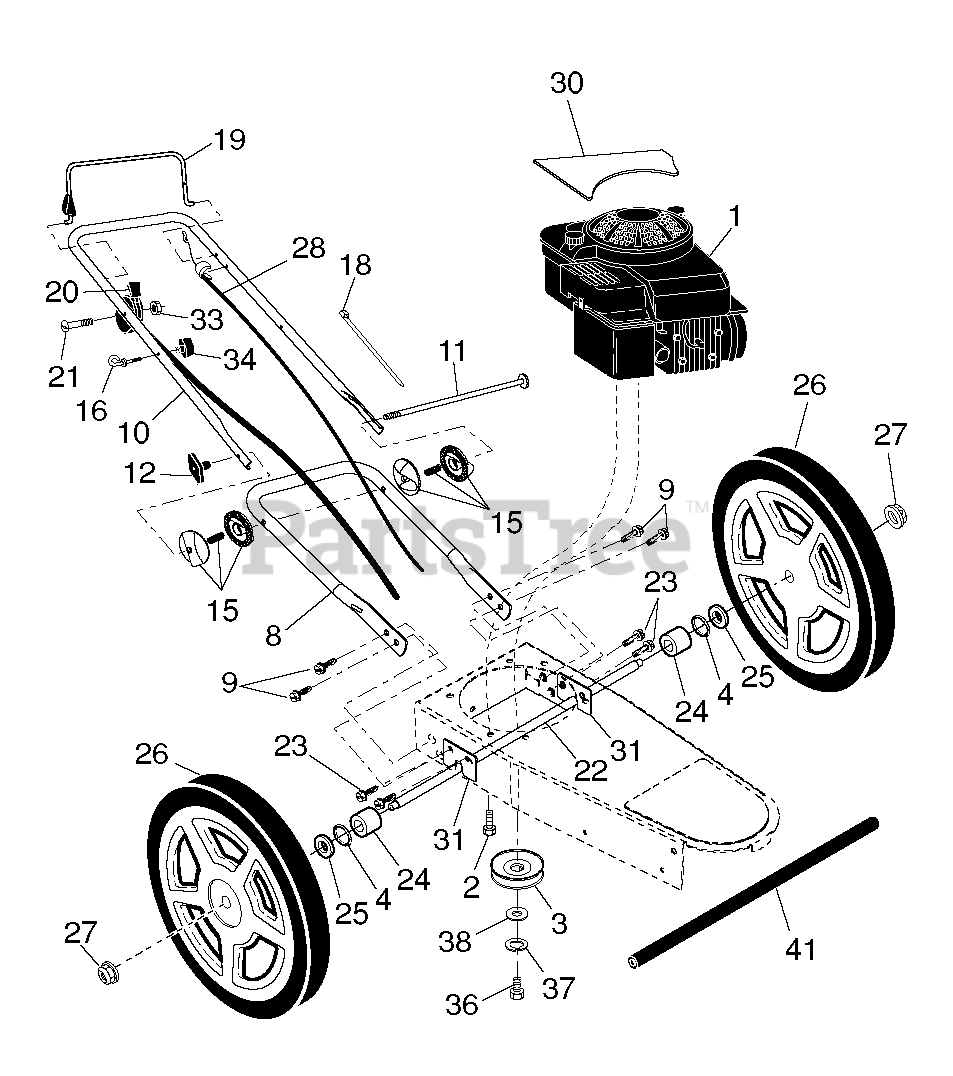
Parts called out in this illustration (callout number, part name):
2	BOLT 3/8-16X1-1/8
3	PULLEY, ENGINE
4	O-RING..070X.487.NEOPRENE
8	HANDLE.LOWER.STRG.TIMMER.BLACK
9	BOLT.HEX.HD.WASHER.5/16-18X.75
10	HANDLE.UPPER.STRG.TIMMER.BLACK
11	BOLT.HANDLE.WHEELED.TRIMMER
15	ADJSTR.ASSEM.HANDLE.WHLD.TRIMM
16	Rope Guide, Blk Zinc Chrom
18	TIE GUIDE
19	BAIL.ASM.ASM.TRIMMER.YELLOW
20	CONTROL.THROT.S-TRIM.SNPIN.B&S
21	SCREW.PAN.HEAD
22	AXLE.TRIMMER
23	BOLT.HEX.HD.WASHER.5/16-18X.75
24	SPACER.AXLE.STRING.TRIMMER
25	WASHER PM
26	WHEEL.12X1.75.5SPK.BB.BLACK
27	NUT.HEX.FLANGE.3/8-16.LOCKNUT
28	Drive Cable, Trimmer
30	DECAL.TRIMMER.WARNING.CE
31	BRACKET, AXLE
33	NUT
34	T-KNOB.NEW ROPE GUIDE
36	SCREW, HEX HD 3/8-24 X 1-3/8
38	WASHER,HARDEN
41	TUBE.AXLE.TRIMMER.BLACK
